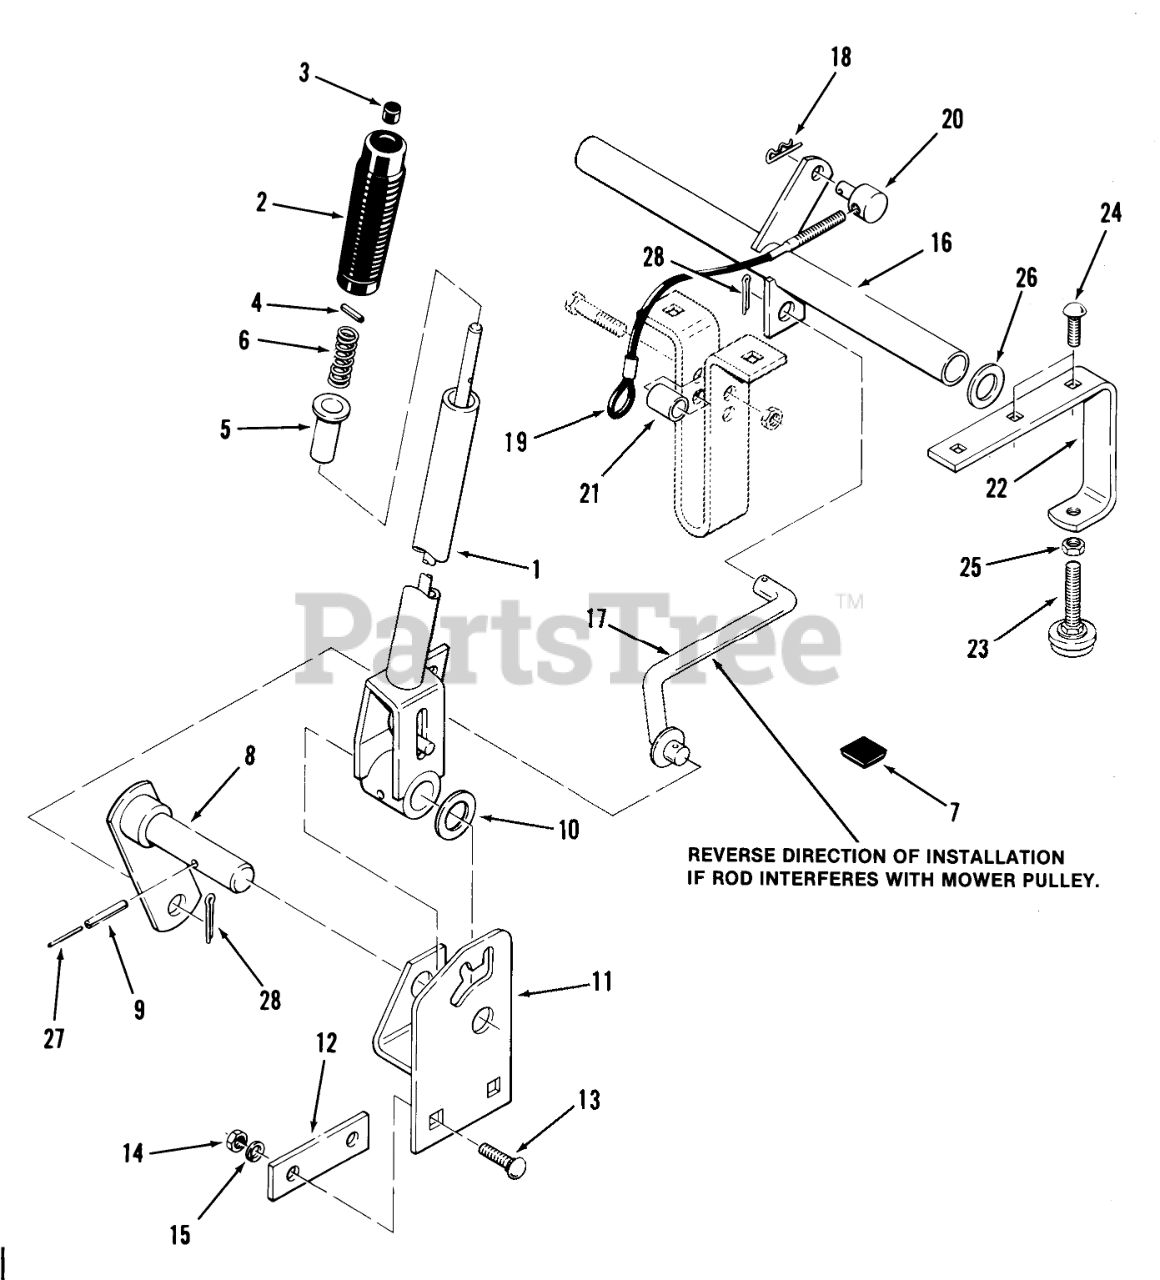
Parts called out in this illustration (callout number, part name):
1	ASSY-HANDLE
2	HANDGRIP
3	CAP-ROD, PLUNGER
4	PIN-SPIROL
5	RETAINER-SPRING
6	SPRING-COMPRESSION
7	BUMPER
8	Lift Arm
9	ROLL PIN 1/4 X 1-1/4
10	RACE
11	ASSY-QUADRANT
12	Spacer
13	Bolt
14	Nut
15	Bolt
16	ASSY-LIFT TUBE
17	ROD-CONNECTING
18	Hairpin Cotter
19	Lift Cable
20	TRUNNION-CLUTCH ROD
21	SPACER
22	BRACKET-BUMPER
23	LEVELER MOWER
24	Bolt-Carriage
25	Nut
26	WASHER
27	PIN-SPIROL
28	Cotter Pin
